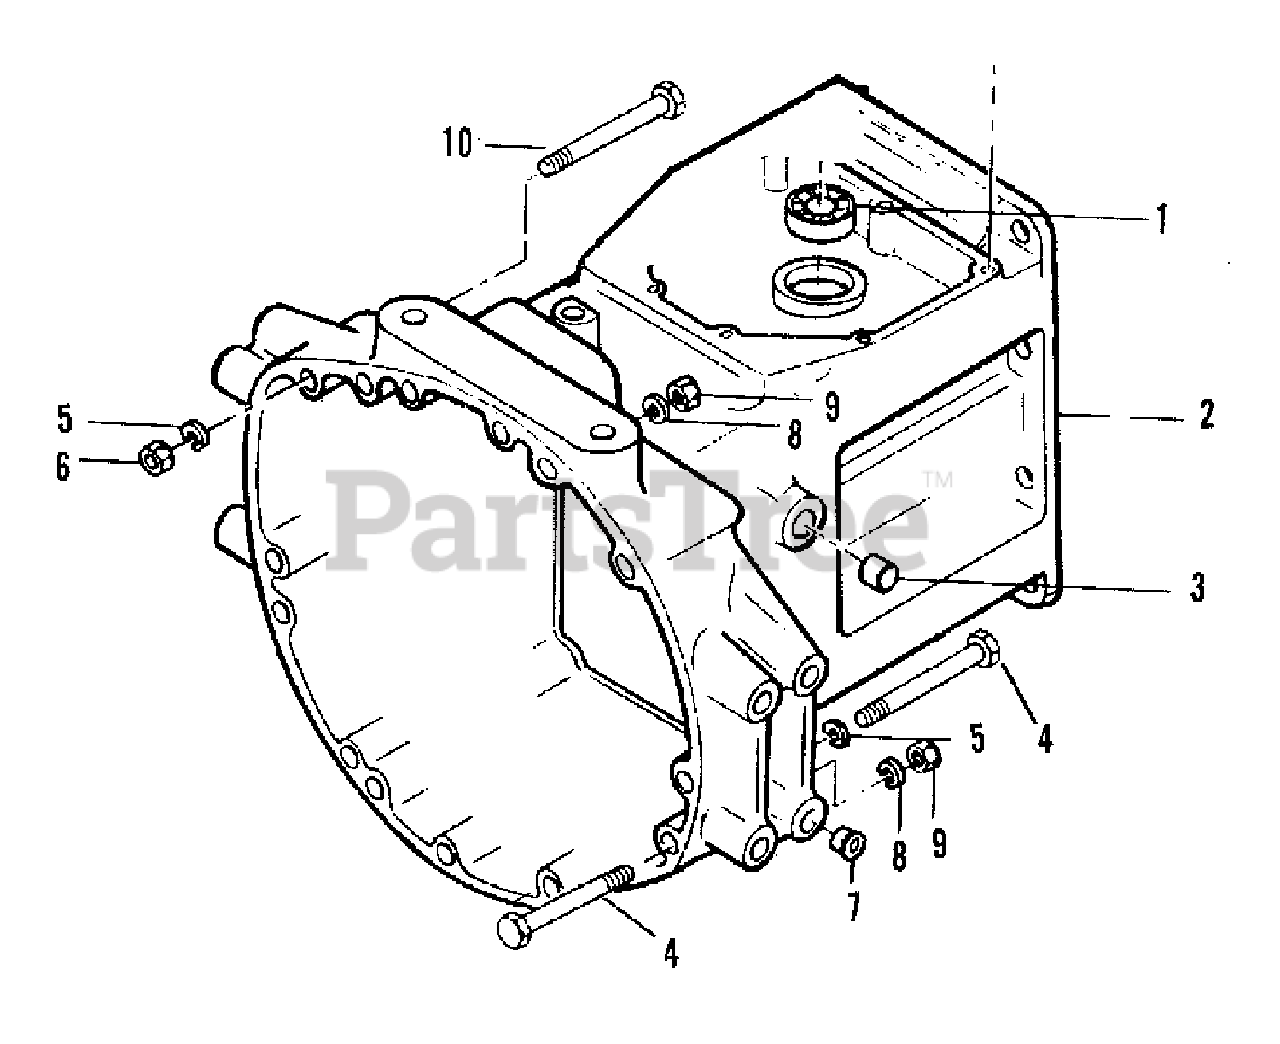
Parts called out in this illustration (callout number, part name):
2	HOUSING, clutch
5	LOCKWASHER, M10
8	LOCKWASHER, M12
